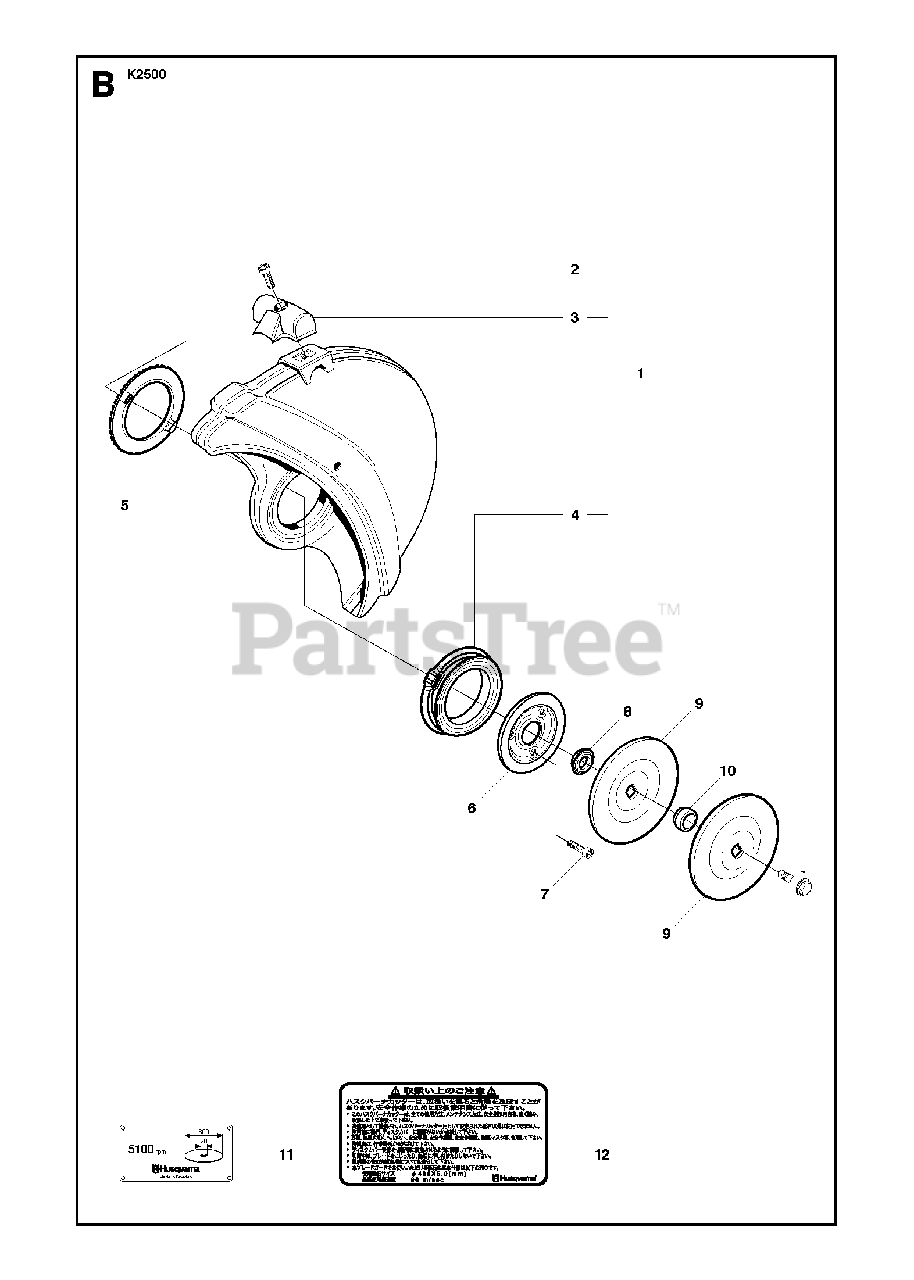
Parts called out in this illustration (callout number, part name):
1	BLADE GUARDIncl. 2 - 4
2	SCREW ITXSCM
7	SCREW ITXSCMNew Part
8	SUPPORT FLANGE
9	FLANGE WASHERDiam 105mm
9	FLANGE WASHERDiam 119mm
10	KITDiam 20mm
10	KITDiam 22,2mm
10	KITDiam 25,4mm
10	BUSHINGDiam 30,5mm
11	LABELDiam 20mm
11	LABELDiam 25,4mm
12	DECAL"16"", Japan only (New Part)"
